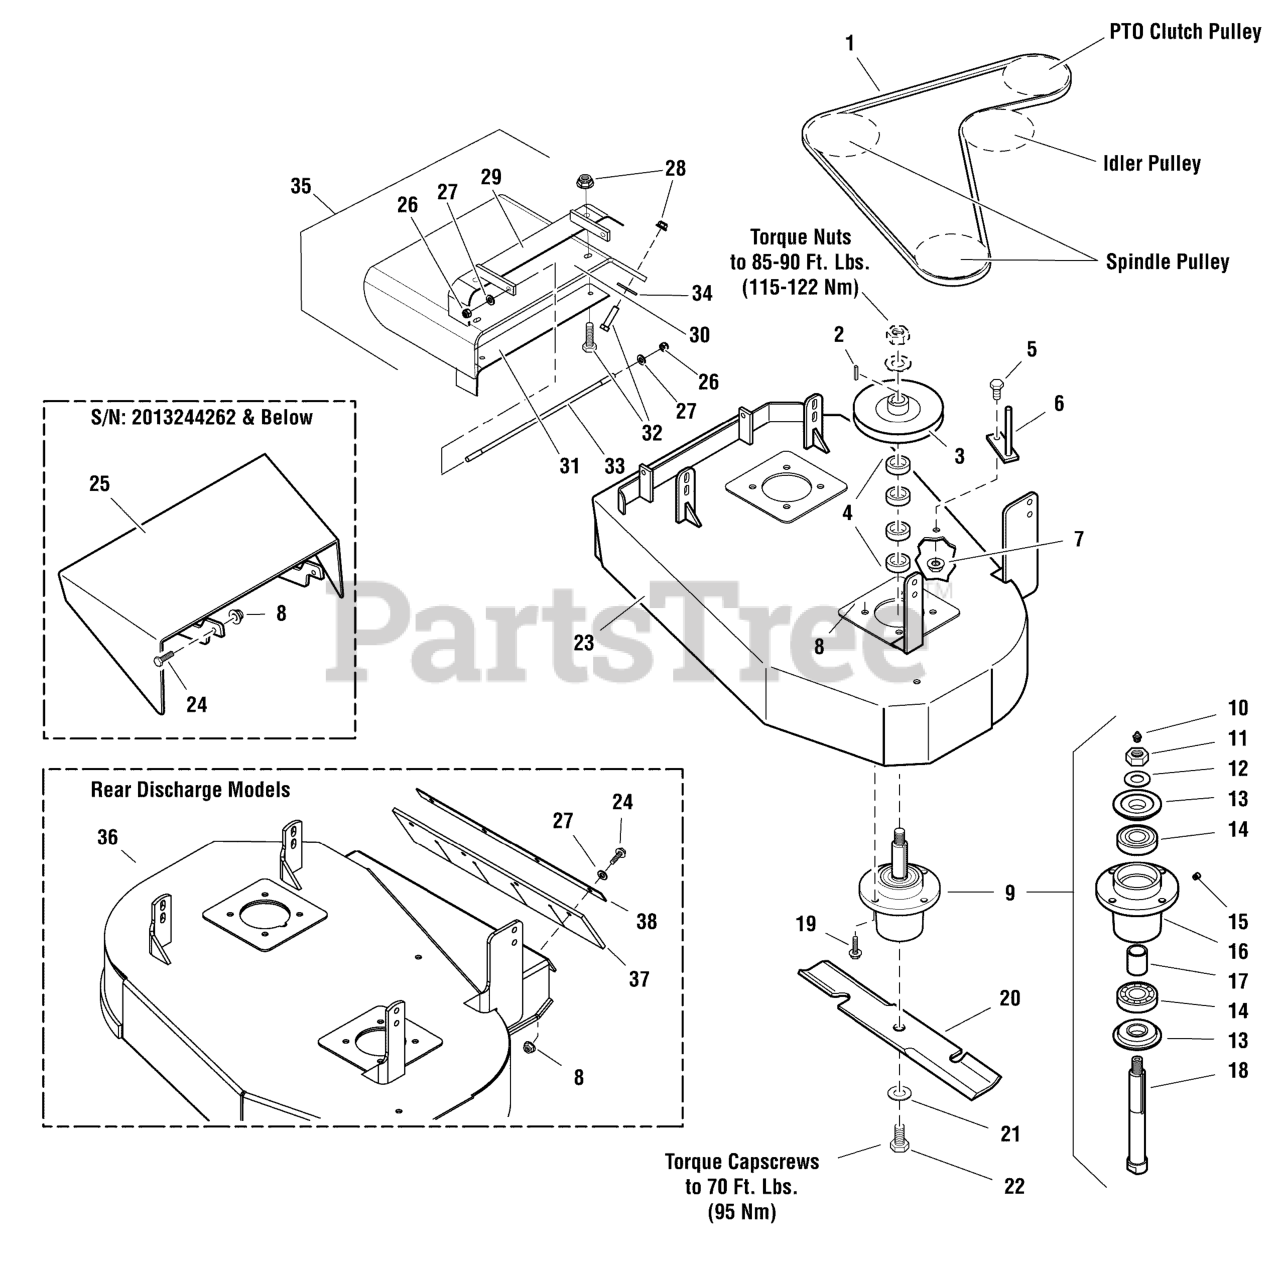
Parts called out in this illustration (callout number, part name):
1	BELT
2	KEY, 1/4 SQ X 1
3	SPINDLE PULLEY
4	SPACER, 1.02 X 1.56 X .50
5	BOLT, 3/8-16 X 1" GD5 CZ
6	BELT GUIDE
7	NUT, 1/4-20 HEX SERR. FLANGE
8	NUT, 5/16-18 Hex Nylock Flange
9	SPINDLE ASSM, ALUMINUM, LONG SHAFT
10	GREASE FITTING
11	NUT, 3/4-16 Hex
12	WASHER, 3/4 BELLEVILLE
13	TRASH SHIELD
14	BEARING
15	RELIEF VALVE
16	SPINDLE HOUSING
17	SPACER, 1.00 X 1.25 X 1.75
18	SPINDLE SHAFT
19	BOLT, Flange Head, 5/16-18 x 1-1/4
20	MOWER BLADE, 16-1/4"
21	WASHER, 5/8" USS
22	BOLT, 5/8-11 X 1-3/4 GD8
23	DECK SHELL W/DECALS, 32 HYDROCUT
24	BOLT, 5/16-18 X 1 GD5 YZ
25	WELD, DISCHARGE CHUTE
26	NUT, 5/16-24 HEX NYLON LOCK
27	WASHER, 5/16" SAE
28	NUT, 3/8-16 HEX NYLOCK FLANGE
29	BRACKET, CHUTE SUPPORT - RED
30	CHUTE, RUBBER
31	BRACKET, CHUTE SUPPORT - BLK
32	BOLT, 3/8-16 X 1-1/2" GD5 CZ
33	ROD, CHUTE PIVOT
34	WASHER, .390 X 1.50 X .109, YZ
35	ORDER INDIVIDUAL PIECES TO SERVICE DISCHARGE CHUTE COMPONENTS
36	WELD, MOWER DECK, 32RD - RED
37	FLAP, RUBBER, 32RD
38	PLATE, RETAINING, 32RD - RED
